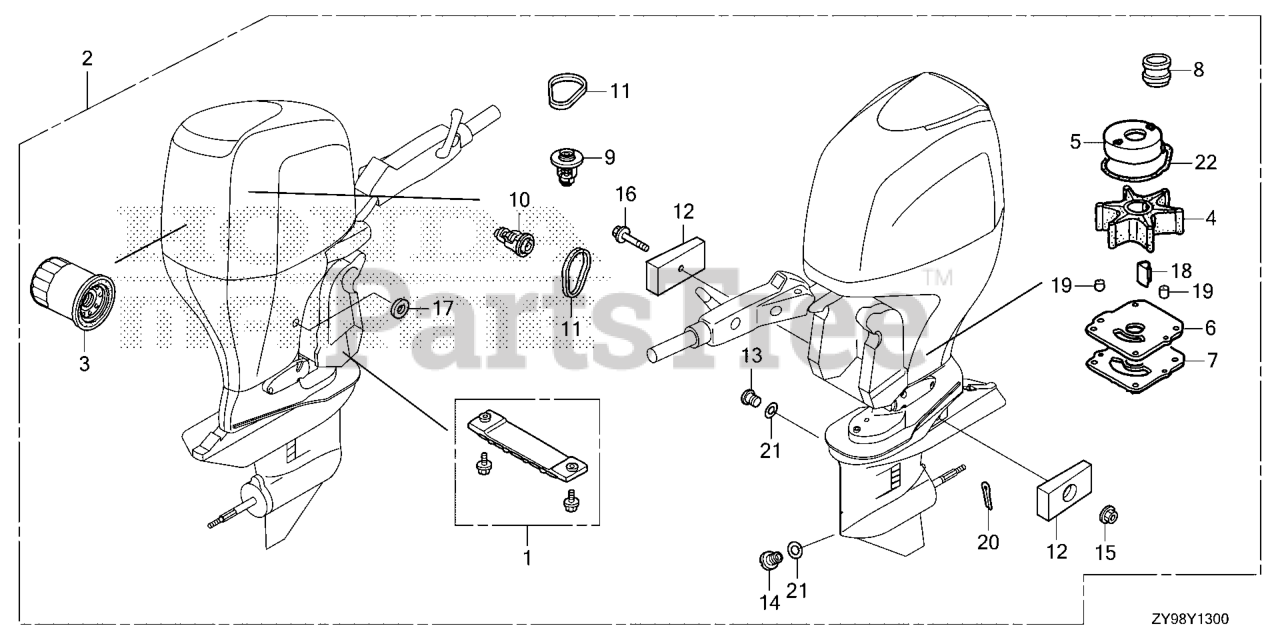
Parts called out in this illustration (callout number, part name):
1	METAL KIT, ANODE Use from Frame SN 4800343.
2	KIT (200)
3	FILTER, OIL
4	IMPELLER, PUMP
5	LINER, PUMP
6	COVER, IMPELLER
7	GASKET B, IMPELLER
8	RING, WATER TUBE SEAL
9	THERMOSTAT ASSY.
10	THERMOSTAT ASSY.
11	O-RING, THERMOSTAT COVER
12	METAL, ANODE
13	BOLT, OIL CHECK
14	BOLT, DRAIN PLUG
15	NUT, SELF-LOCK (6MM)
16	BOLT, FLANGE (6X35)
17	WASHER, DRAIN PLUG (12MM)
18	KEY, WOODRUFF
19	PIN, DOWEL (6X10)
20	PIN, SPLIT (4.0)
21	O-RING (6.9X1.45)
22	O-RING, WATER PUMP
